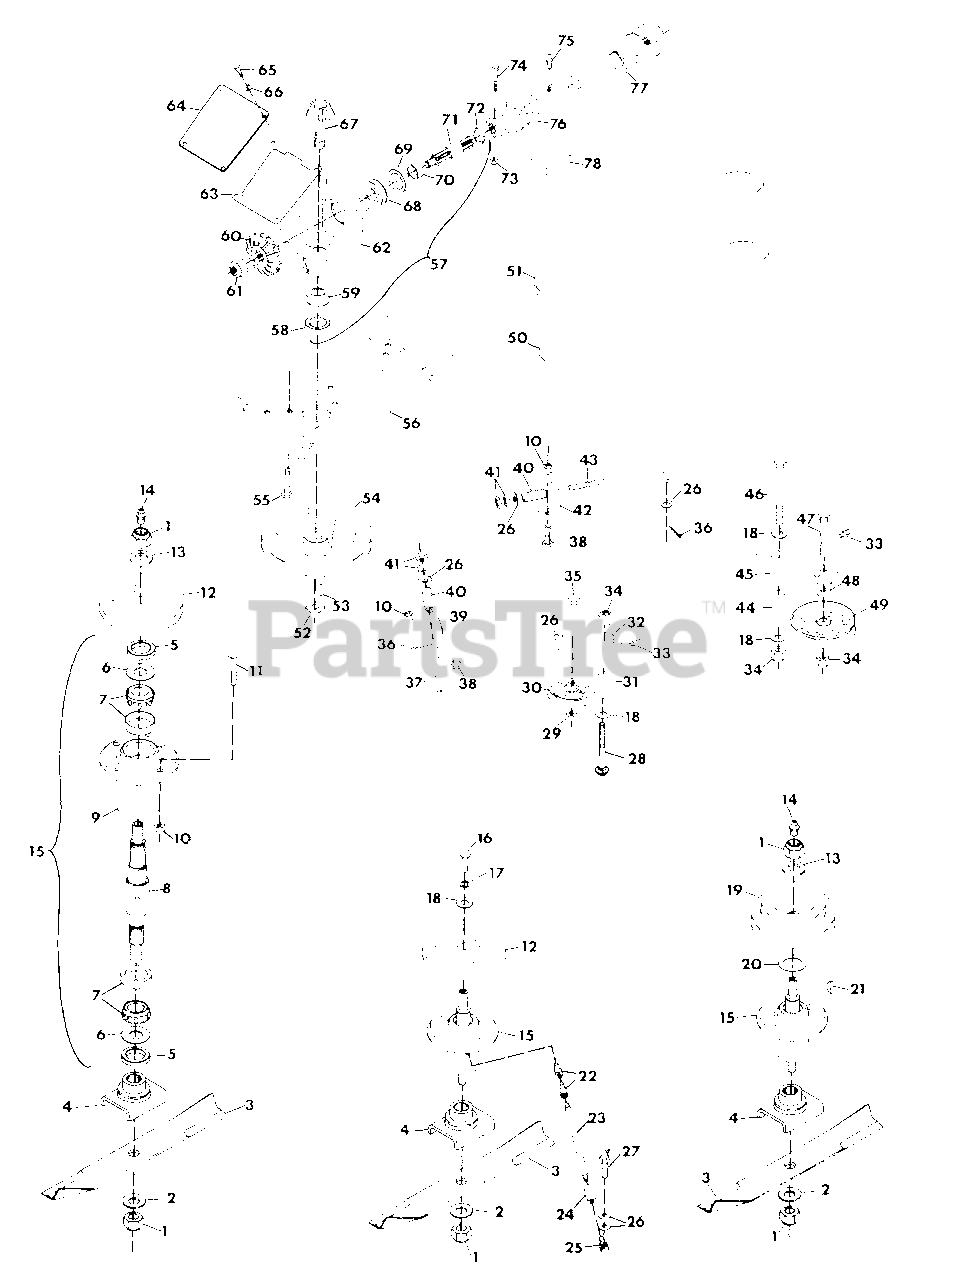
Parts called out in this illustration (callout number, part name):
1	NUT, LOCK 5/8-11
2	WASHER, FLAT .656X1.312X.095
3	BLADE
4	WELDMENT, BLADE CRADLE
5	SEAL, STEEL(RIGHT AND CENTER SPINDLES)
5	SEAL, STEEL(LEFT SPINDLE)
6	WASHER, FLAT .975X1.970X.030(RIGHT AND CENTER SPINDLES)
6	WASHER, FLAT .975X1.970X.030(LEFT SPINDLE)
7	ASSEMBLY, BEARING CUP AND CONE
8	SHAFT, SPINDLE(RIGHT SPINDLE)
8	SHAFT, SPINDLE(CENTER SPINDLE)
8	SHAFT, SPINDLE(LEFT SPINDLE)
9	HOUSING, BEARING(LEFT AND RIGHT SPINDLES)
9	HOUSING, BEARING(CENTER SPINDLE)
10	NUT, LOCK 3/8-16
11	BOLT, 3/8-16X1.375 RD HD SQ NK
12	PULLEY
13	WASHER, FLAT .687X1.312X.122
14	FITTING, LUBE 1/8
15	ASSEMBLY, SPINDLE(RIGHT)
15	ASSEMBLY, SPINDLE(LEFT)
16	BOLT, HEX SPECIAL 1/2-13X1.34
17	WASHER, LOCK 1/2 REG.
18	WASHER, FLAT .500X1.250X.083
19	PULLEY, DRIVE
20	RACE, BEARING THRUST
21	KEY, WOODRUFF .25X1.00 HARD #15
22	ELBOW, STREET 1/8-26(CENTER SPINDLE)
23	NIPPLE, PIPE 6.30
24	COUPLING, PIPE 1/8-27
25	ELBOW, ADAPTOR 90 DEG.
26	WASHER, FLAT .406X.812X.065
27	FITTING, LUBE 65 DEG.
28	BOLT, 1/2-13X3.5 RD HD SQ NK
29	NUT, LOCK 3/8-16
30	SHEAVE, IDLER
31	SPACER, .850X.546X2.18
32	WELDMENT, IDLER PIVOT
33	FITTING, LUBE 1/4-28
34	NUT, LOCK 1/2-13
35	BOLT, HEX 3/8-16X1.75
36	PIN, COTTER .06X1.000
37	ROD, IDLER
38	BOLT, HEX 3/8-16X1.00
39	SUPPORT, SPRING
40	SPRING, COMP. 1X.78X338
41	NUT, HEX 3/8-24
42	SUPPORT, SPRING
43	ROD, IDLER
44	SPACER, .850X.546X2.50
45	WELDMENT, IDLER PIVOT
46	BOLT, HEX 1/2-13X3.75
47	BOLT, HEX 1/2-13X2.00
48	SPACER, .516X.875X.300
49	PULLEY, FLAT IDLER
50	BELT, "B"
51	BELT, "A"
52	NUT, JAM 3/4-10 HEX HEAVY
53	KEY, WOODRUFF 3/16X5/8 NO. 61
54	PULLEY, GEARBOX
55	BOLT, HEX 1/2-13X1.00
56	PLATE, SUPPORT
57	ASSEMBLY, DRIVE
58	SEAL, OIL
59	ASSEMBLY, BEARING
60	GEAR, BEVEL
61	NUT, LOCK 3/4-10
62	CASTING, GEAR BOX
63	GASKET, GEAR HOUSING
64	COVER, GEAR HOUSING
65	BOLT, HEX 1/4-20X.50
66	WASHER, LOCK 1/4 REG.
67	SHAFT, GEAR PINION
68	ASSEMBLY, BEARING
69	SEAL, OIL
70	SPACER
71	SHAFT
72	RING, RETAINING 1.000 SHAFT
73	NUT, LOCK 1/4-20
74	BOLT, HEX 1/4-20X2.25
75	FITTING, LUBE 1/4-28
76	JOINT, U FEMALE
77	SHAFT, PROP. SQ. BAR
78	KIT, REPAIR U-JOINT
